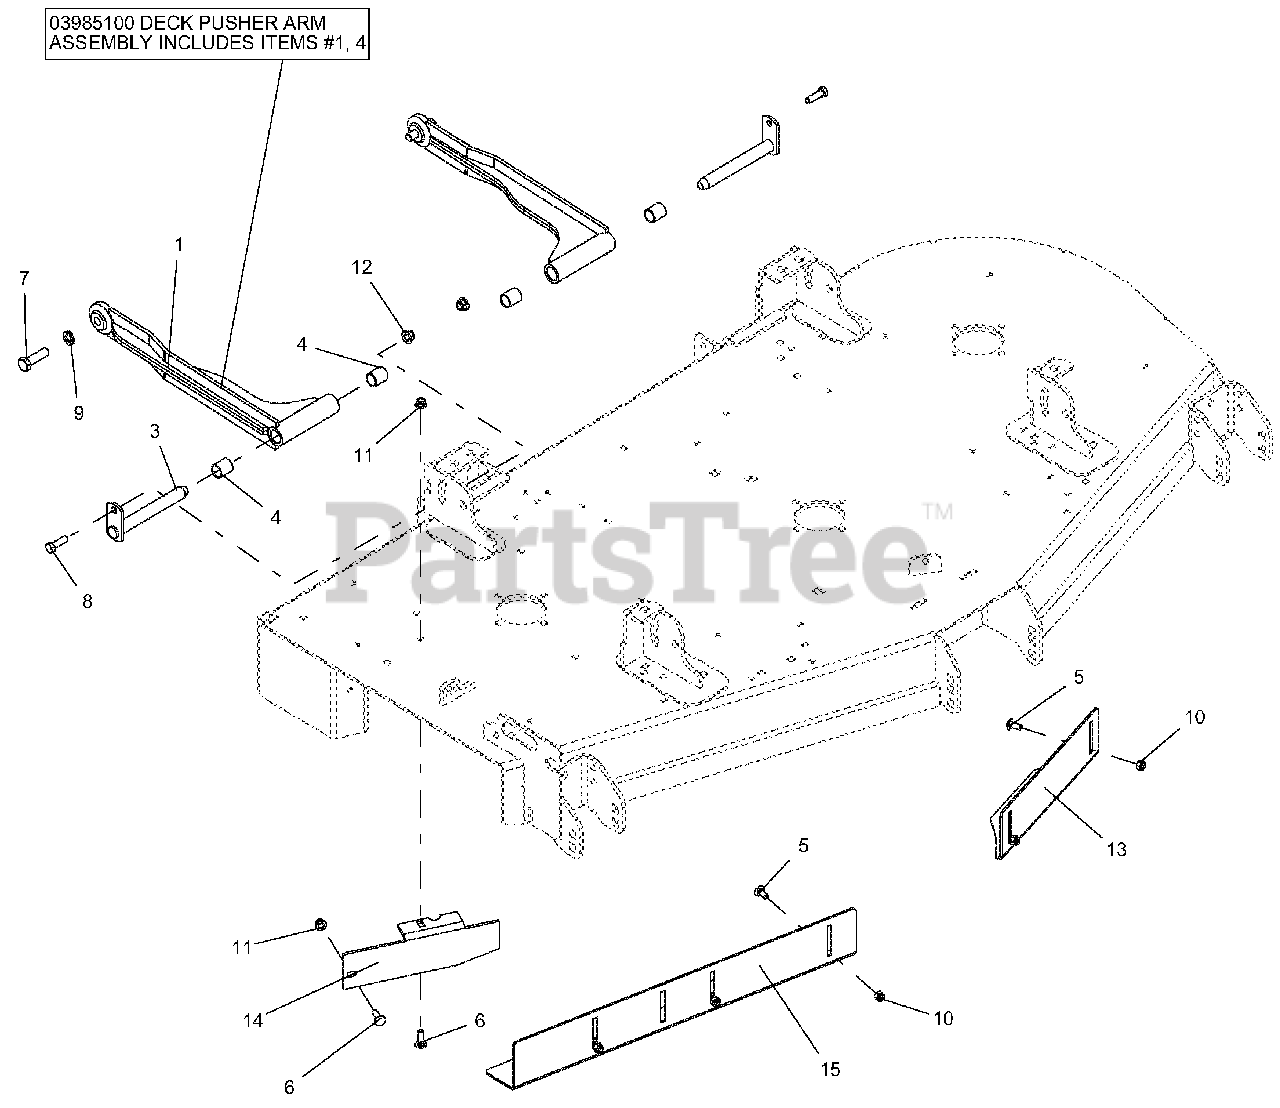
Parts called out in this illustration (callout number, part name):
1	WMT, DECK STABILIZER ARM-BLACK
1	DECK PUSHER ARM ASSEMBLY INCLUDES ITEMS #1, #4
3	WLDMT, MOWER MTG. PIN
4	BRG, .75 X .875 X 1.00
5	BLT-RDHDSQNK .31-18X.75 G5 YWZC
6	BLT-RDHDSQSHNK .31-18X1.00 G5 Y
7	BLT-HEX .50-13X1.75 GR5 YWZC EP80
8	BLT-HEX .38-16X1.25 GR5 YWZC
9	WSHR-LK .50X.125 REG YWZC
10	NUT-LK-NYL .312-18 YWZC
11	NUT-LK-NYL-FLG .31-18 YWZC
12	NUT-LK-NYL-FLG .38-16 YWZC
13	BAFFLE, 60" LH VACUUM
14	BAFFLE, 60" DISCHARGE
15	BAFFLE, 60" RH VACUUM
